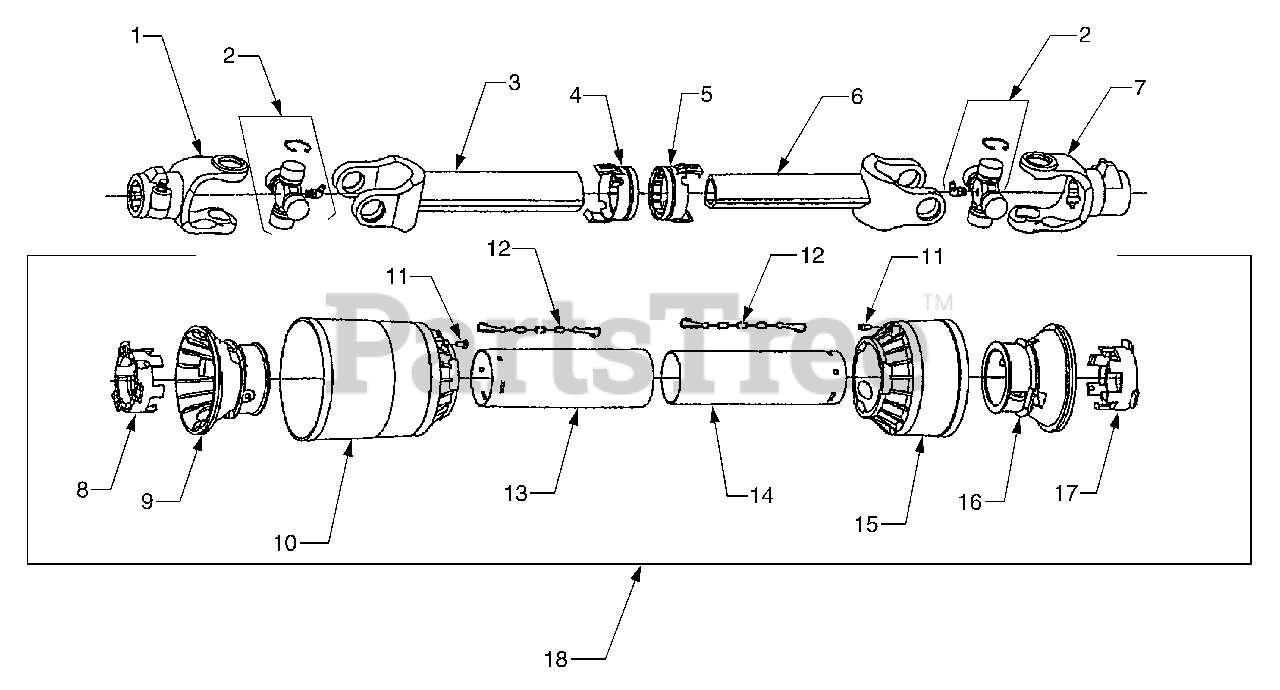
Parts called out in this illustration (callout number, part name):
1	Yoke Assembly
2	Cross and Bearing
3	Outside Tube w/Yoke
4	Outer Fastener Ring
5	Inner Fastener Ring
6	Inner Tube w/Yoke
7	Yoke Assembly
8	Tube Bearing Outer
9	Outer Tube Rigid Cone
13	Outer Shield
14	Inner Shield
16	Inner Tube Rigid Cone
17	Tube Bearing Inner
18	Shield Complete
